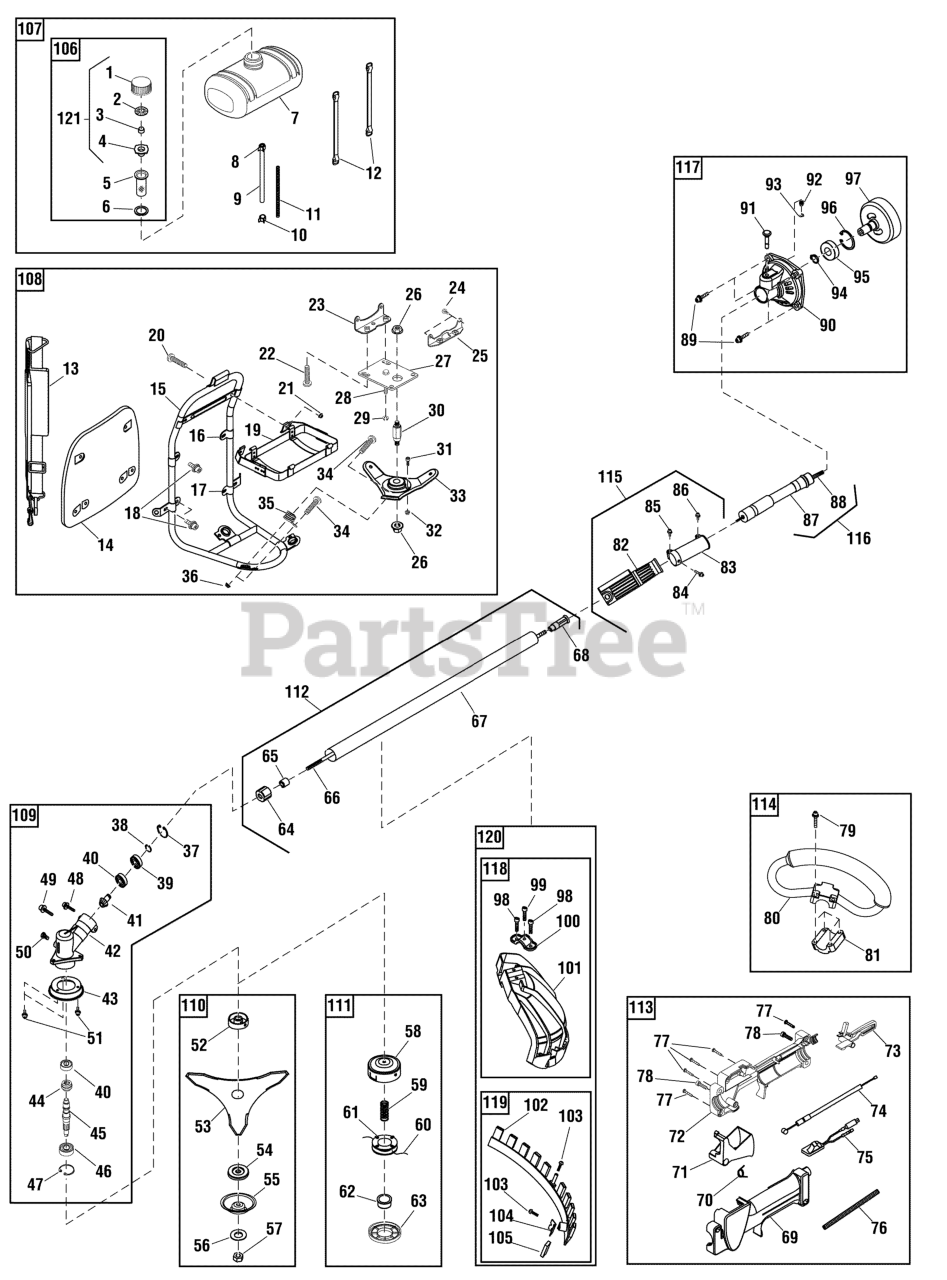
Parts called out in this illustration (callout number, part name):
1	CAP, Fuel Tank
2	LID, Inner, Fuel Tank
3	NET, Fuel Filter
4	LID, Inner, Rubber
5	FUEL FILTER ASSEMBLY
6	GASKET, Filter
7	FUEL TANK
8	CLAMP, Fuel Hose, Upper
9	FUEL PIPE
10	CLAMP, Fuel Hose, Lower
11	SPRING, Fuel Pipe Protection
12	BELT, Fuel Tank
14	CUSHION, Back
15	BRACKET, Engine
16	BRACKET, Back Cushion, Upper
17	BRACKET, Back Cushion, Lower
18	BOLT, M5 x 16
19	BRACKET ASSEMBLY, Fuel Tank
21	NUT, M5
22	BOLT, M6 x 16
23	BRACKET, Front
24	BOLT, M5 x 16
25	BRACKET, Rear
26	NUT, M10
27	PLATE, Bracket
28	BOLT, M6 x 40
29	NUT, M6
31	BOLT, M5 x 12
32	NUT, M5
33	SEAT ASSEMBLY
34	BOLT, M6 x 16
35	SPRING
36	NUT, M6
39	BEARING
41	PINION
42	CASE, Gear Box
43	COVER, Blade
44	GEAR
45	SPLINE SHAFT
46	BEARING
50	BOLT, M6 x 12
51	BOLT, M5 x 10
52	GASKET, Spline
54	HOLDER
55	PROTECTOR, Blade
56	WASHER, Wave, Dia 10
58	BUMP HEAD BOX
59	SPRING, Bump Head
60	ROPE, Bump Head
61	ROPE BOX
62	PUSH COVER, Bump Head
63	COVER, Bump Head
64	COVER, Drive Shaft, Rubber
65	OIL BEARING
66	DRIVE SHAFT
67	SHAFT, Straight
68	COUPLING
69	COVER, Handle, Control Switch, LH
70	SPRING, Torsion
71	LEVEL, Throttle
72	COVER, Handle, Control Switch, RH
73	HANDLE, Self Lock
74	CABLE, Comp.
75	STOP BUTTON
76	COVER, Shaft
77	SCREW, ST3.5X19
78	BOLT, M5 x 18
79	BOLT, M5 x 24
80	HANDLE
81	HOLDER, Lower
82	COVER, Shaft Connection
83	CONNECTOR, Straight Shaft
85	BOLT, M5 x 20
86	BOLT, M5 x 30
87	FLEXIBLE SHAFT, Outer
88	SHAFT, Flexible, Inner
89	BOLT, M6 x 20
90	CASE, Clutch
92	SPRING
93	STOP RING, 5
97	CLUTCH DRUM, Comp.
98	BOLT, M5 x 12
99	BOLT, M5 x 10
100	HOLDER, Safety
101	GUARD, Blade
102	SECURING SADDLE
103	SCREW, Self Tapping, ST4.2 x 16
105	COVER, Blade
106	KIT, Fuel Cap Assembly
107	KIT, Fuel Tank Assembly
108	KIT, Back Belt Group
109	KIT, Gear Box Assembly
110	KIT, Blade Assembly
111	KIT, Bump Head Assembly
112	KIT, Drive Shaft Assembly
113	KIT, Control Box Assembly
114	Kit, Handle
115	KIT, Shaft Connection, Group
116	FLEXIBLE SHAFT ASSEMBLY
117	KIT, Clutch Assembly
118	BLADE GUARD ASSEMBLY
119	KIT, Securing Saddle Assembly
120	KIT, Blade Guard Assembly
121	LID, Fuel Tank, Comp.
